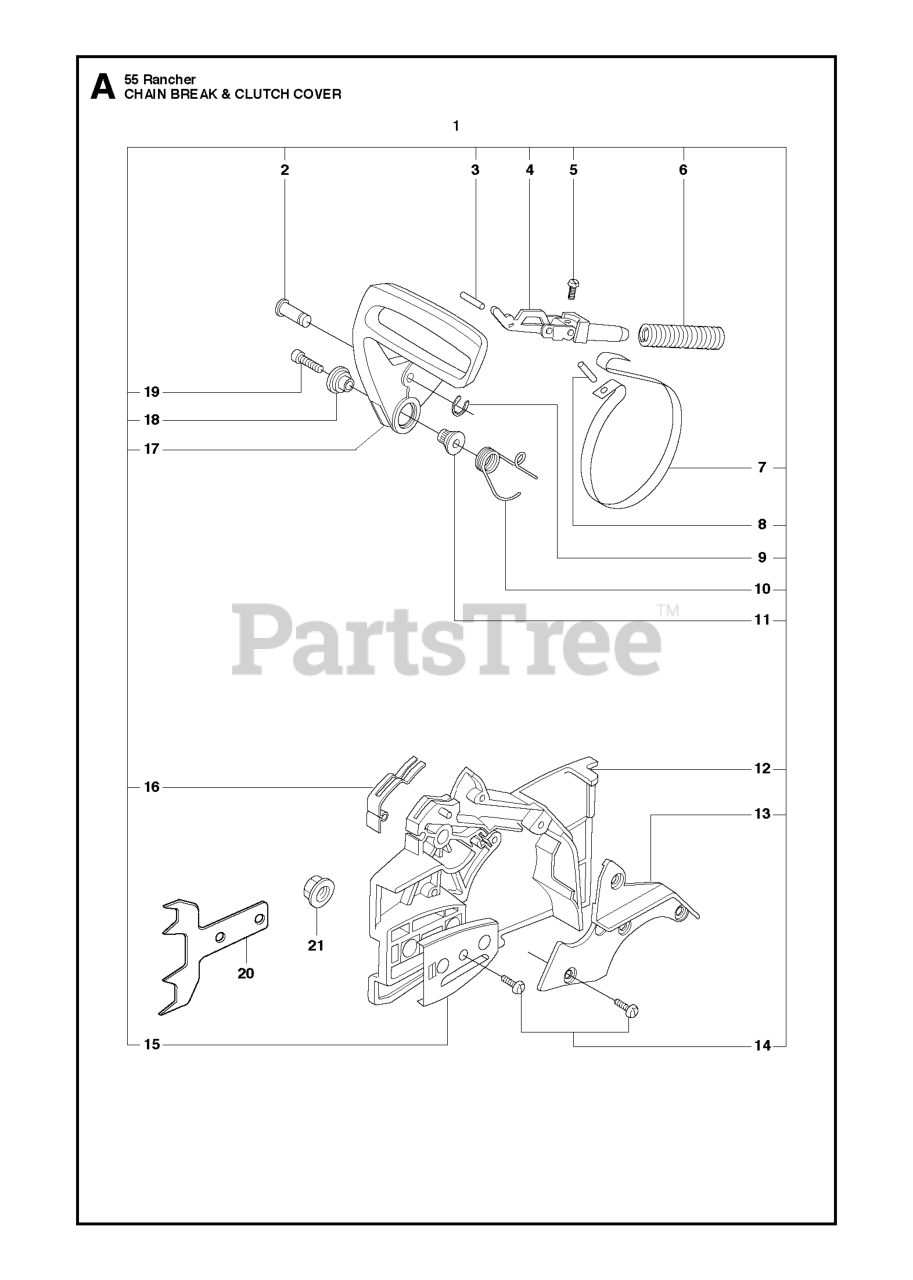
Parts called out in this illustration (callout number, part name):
1	CHAINBRAKE
4	KNEE-JOINT
7	BRAKE BAND
8	SPIRAL PIN 4X12
11	PIVOT SLEEVE L
12	CLUTCH COVER
15	COVERING PLATE
17	HAND GUARD
18	PIVOT SLEEVE R
21	NUT M8 FLANGE
